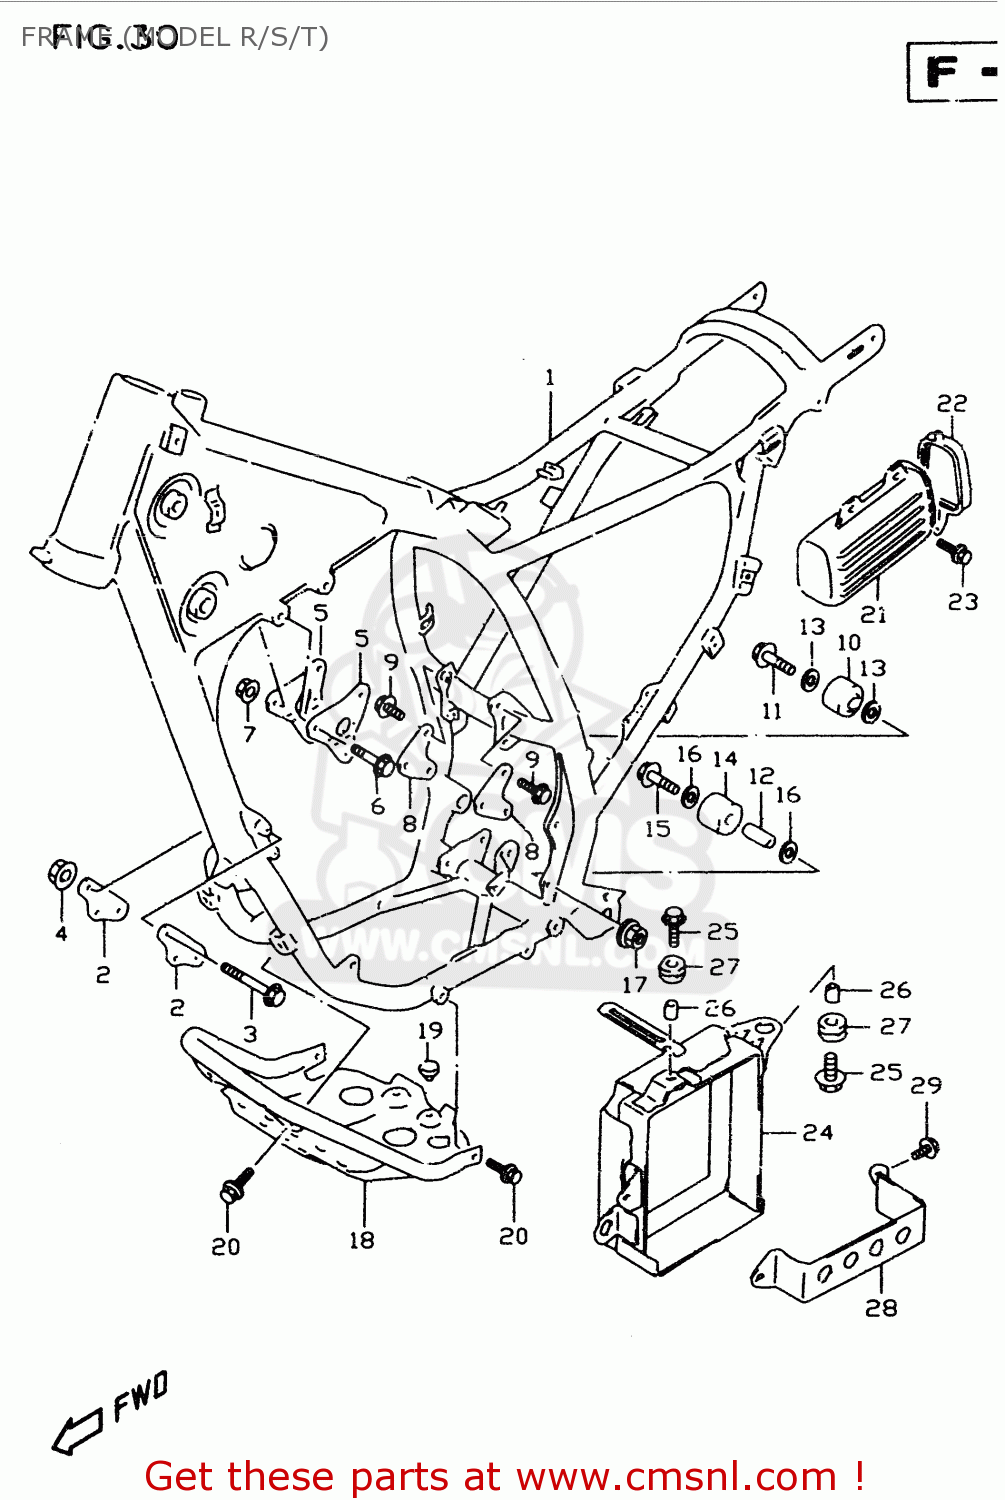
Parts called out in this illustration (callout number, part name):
1	FRAME COMP
2	PLATE,ENGINE MOUNT FR
3	BOLT(8X85)
4	NUT
5	PLATE,ENGINE MOUNT UPR
6	BOLT(8X70)
7	NUT
8	PLATE,ENGINE MOUNTING,REAR
9	BOLT(8X16)
10	ROLLER,CHAIN CONTROL
11	BOLT(8X38)
12	SPACER (8.6X13.8X28)
13	WASHER
14	ROLLER,CHAIN
15	BOLT 8X45
16	WASHER
17	NUT
18	PROTECTOR,ENGINE(SILVER)
19	CUSHION
20	BOLT
21	HOLDER,TOOL
22	CAP,TOOL HOLDER
23	BOLT 6X16
24	HOLDER,BATTERY
25	BOLT(6X20)
26	SPACER (6.8X10X9)
27	CUSHION
28	COVER,BATTERY HOLDER
29	SCREW(6X10)
